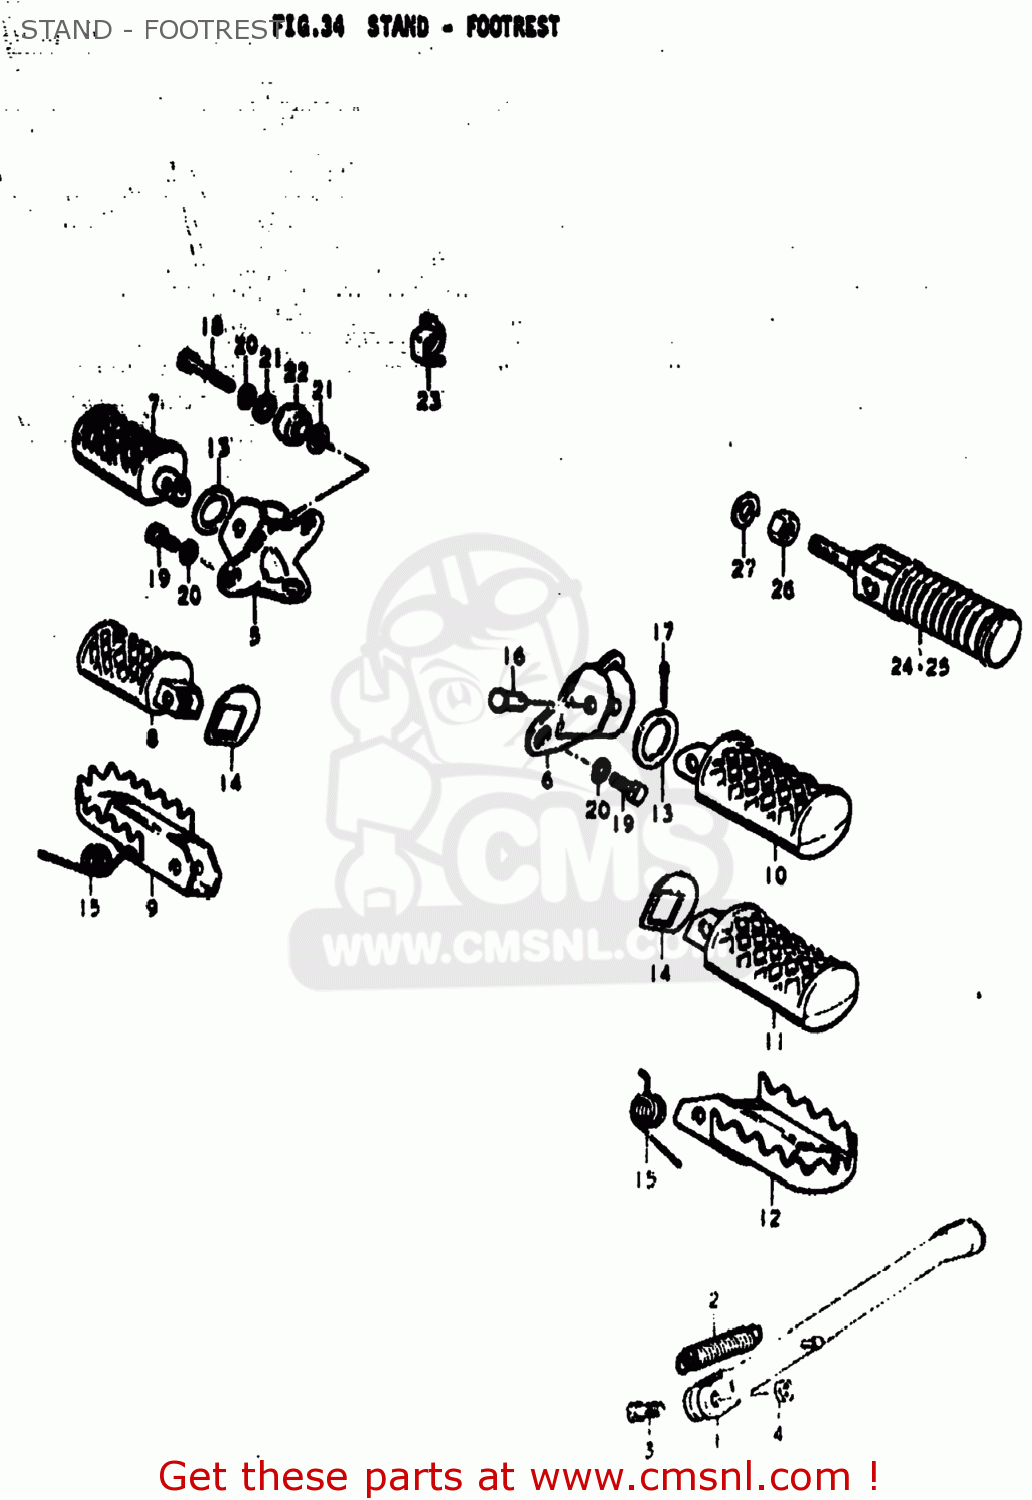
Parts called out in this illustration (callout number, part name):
1	STAND,SIDE
2	SPRING
3	BOLT(10X30)
4	NUT
5	BAR,FRONT FOOTREST
6	HOLDER,FRONT FOOTREST
7	RUBBER,FOOTREST,RIGHT
8	RUBBER,FOOTREST,RIGHT
9	RUBBER,FOOTREST,RIGHT
10	RUBBER,FOOTREST,LEFT
11	RUBBER,FOOTREST,LEFT
12	RUBBER,FOOTREST,LEFT
13	WASHER
14	WASHER
15	SPRING
16	PIN
17	PIN 20X20
18	** SUPERSEEDED
19	BOLT
20	LOCK WASHER
21	WASHER
23	HOLDER
24	FOOTREST ASSEMBLY,REAR
25	FOOTREST ASSY,PILLION
26	NUT
27	WASHER,LOCK 12
